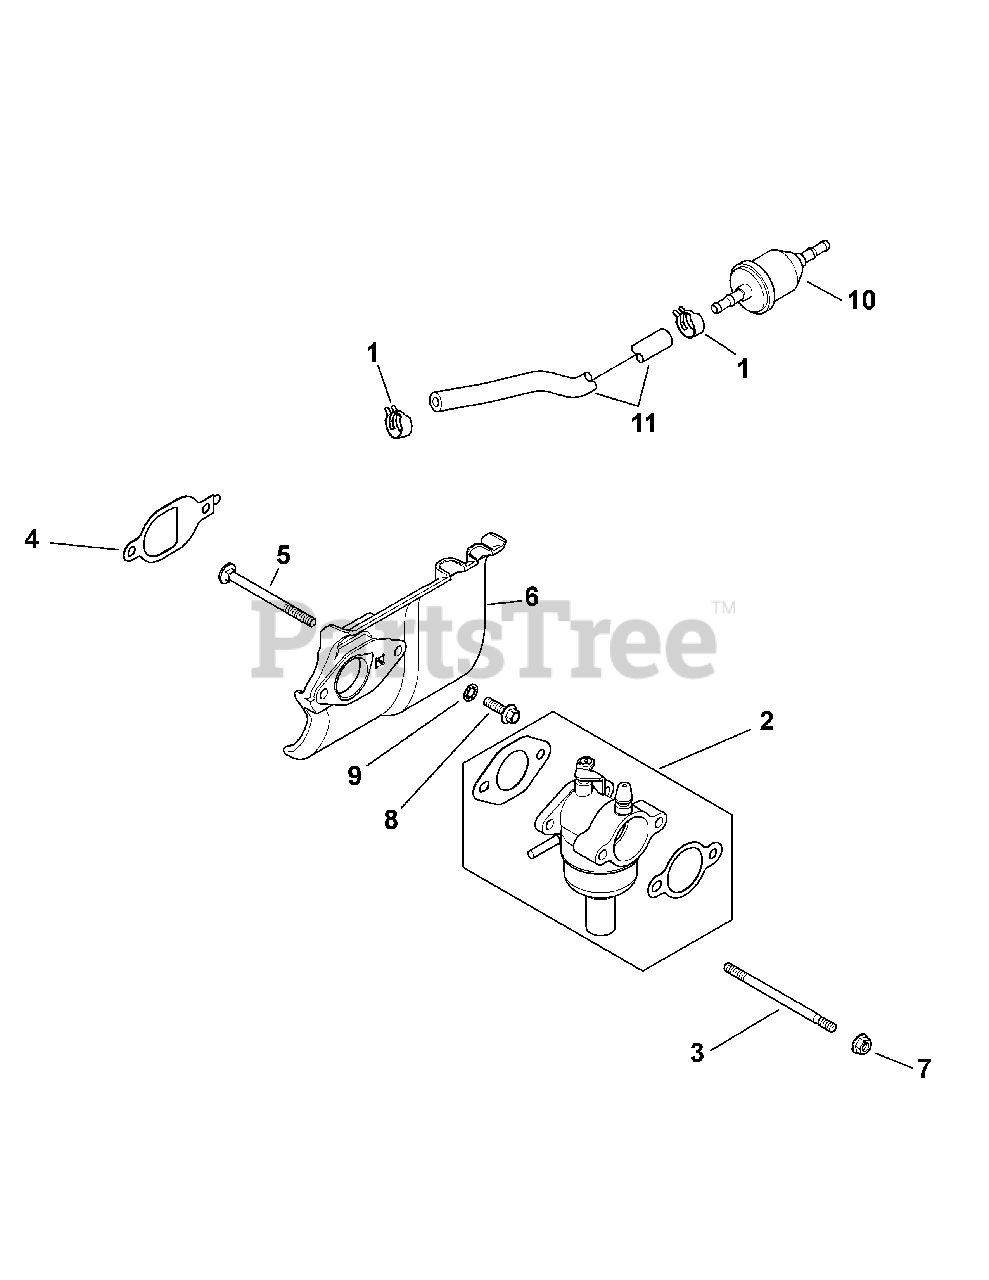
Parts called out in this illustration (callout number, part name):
1	Hose Clamp, 1/2
2	Carburetor Kit
3	Stud, M6 X 1.0 X 100
4	Heat Deflector Gasket
5	Carburetor Stud
6	Heat Deflector Kit
7	Flange Nut, M6 X 1.0
8	Flange Screw, M6 X 1.0 X 20
9	Int. Tooth Lock Washer, 1/4
11	Fuel Line
